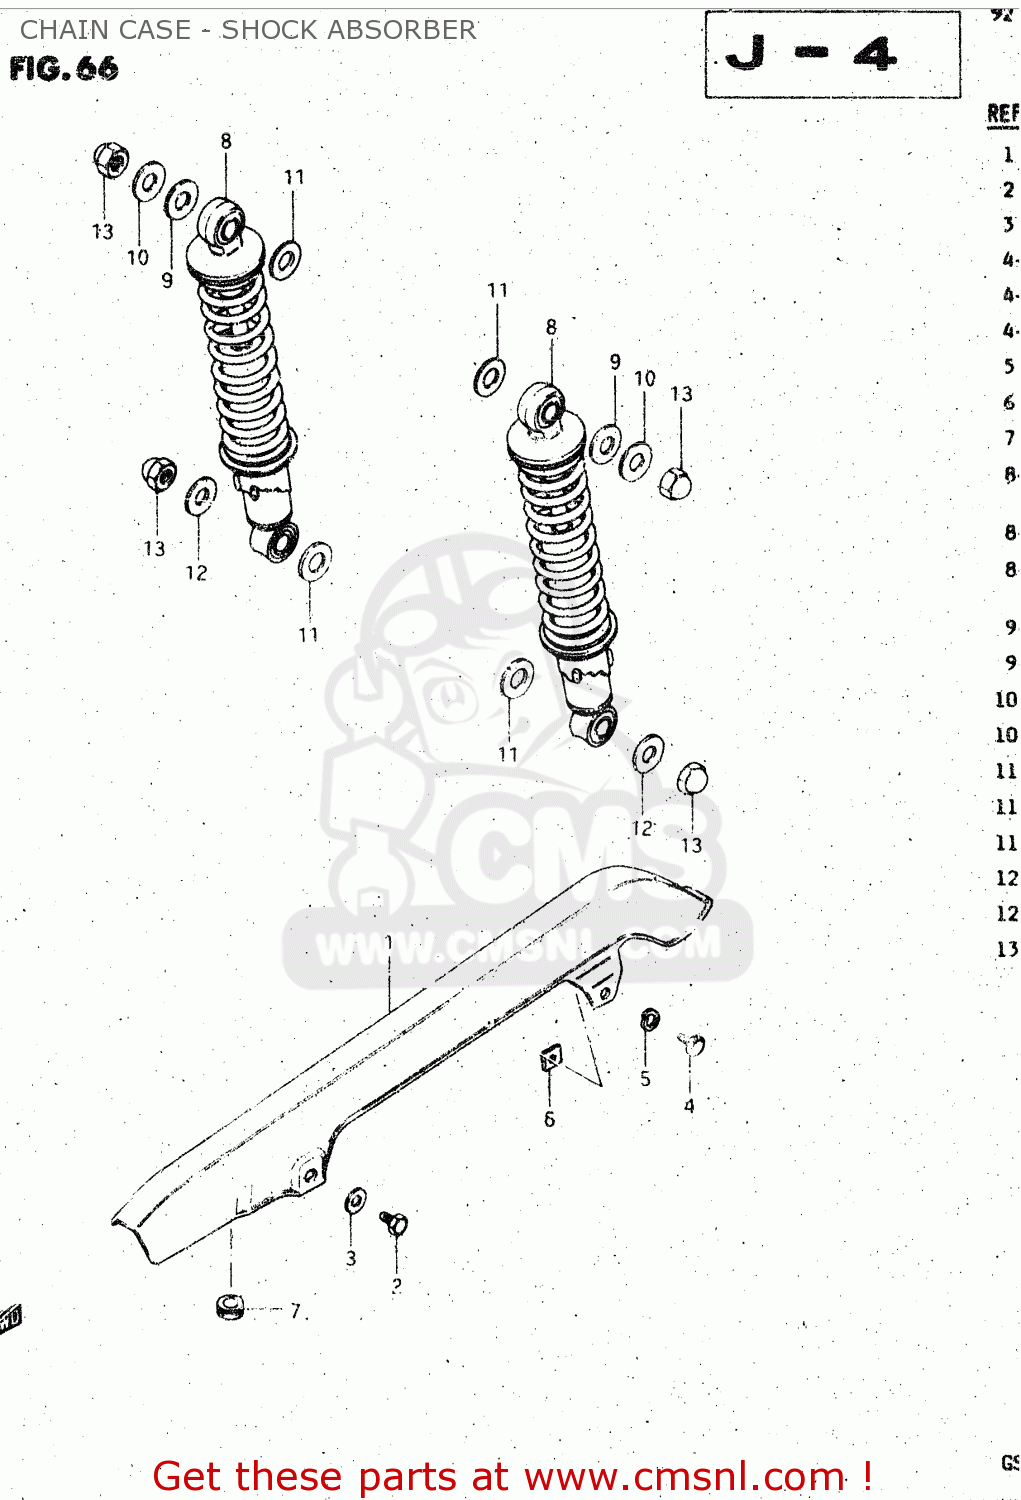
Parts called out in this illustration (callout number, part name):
1	CASE, CHAIN (BLACK)
2	BOLT(6X8)
3	WASHER
4	BOLT
5	WASHER,LOCK
6	NUT,CHAIN CASE RR
7	CUSHION
8	ABSORBER ASSY,RR SHOCK
9	WASHER
10	WASHER
11	WASHER
12	WASHER
13	NUT
